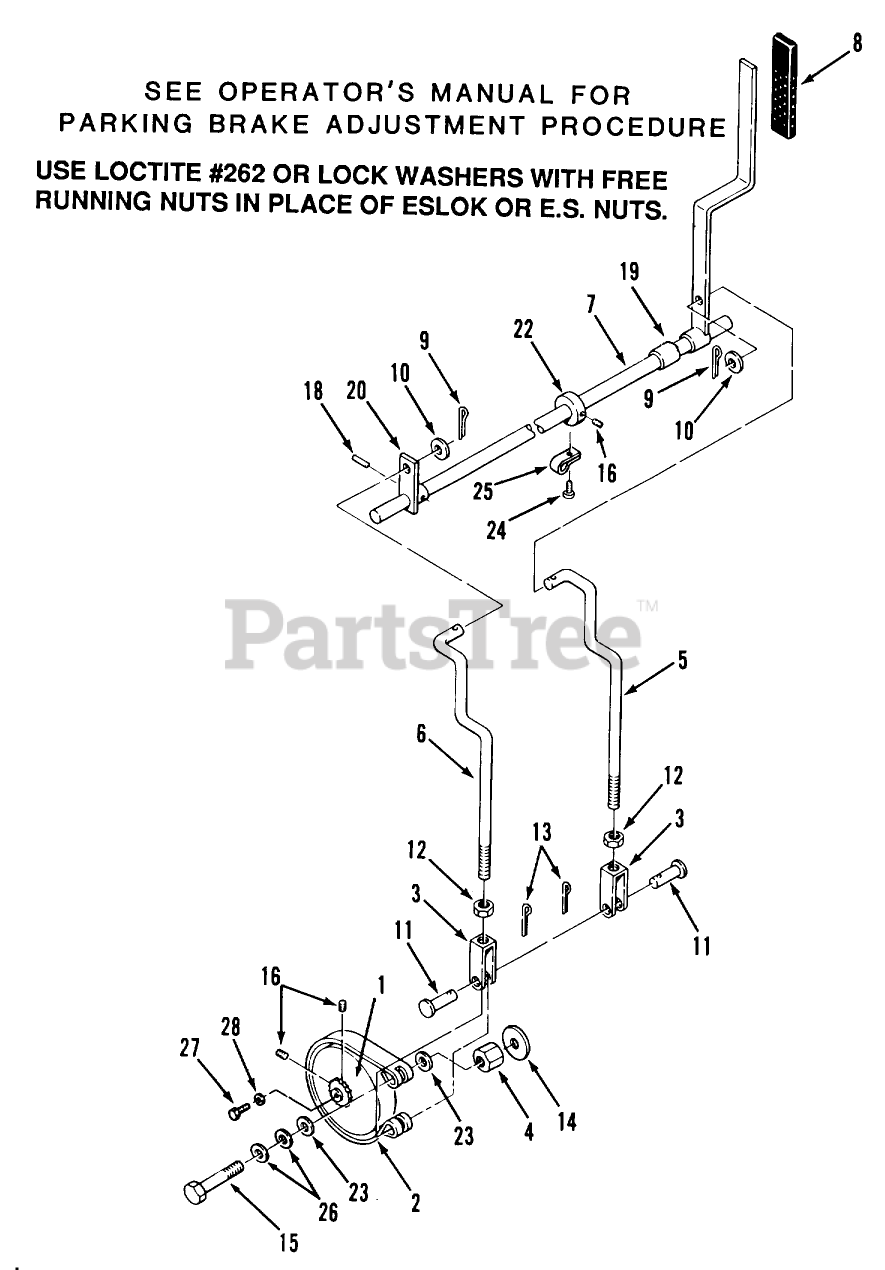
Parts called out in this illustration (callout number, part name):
1	ASS'Y-DRUM SPROCKET
2	BRAKE-BAND
3	ASSY-YOKE BRAKE
4	NUT-COUPLING
5	ROD-BRAKE L.H.
6	ROD-BRAKE R.H.
7	ASSY-PARKING BRK
8	GRIP BRAKE20258-K
9	Cotter Pin
10	WASHER 5/16 SAE
11	Clevis Pin 5/16 x 1 1/4
12	Nut-Lock
13	Cotter Pin
14	WASHER
15	Bolt
16	SCREW-SET
17	Clevis Pin 5/16 x 7/8
18	Roll Pin
19	SPACER-PARKING BR B
20	ASSY-PARKING BRK B
22	COLLAR-BRAKE SWIT B
23	Washer
24	PAN HD SCRW-#10 -1/4
25	CLAMP-MERCURY SWITCH
26	WASHER-SPRING
27	H H C S
28	WASHER
